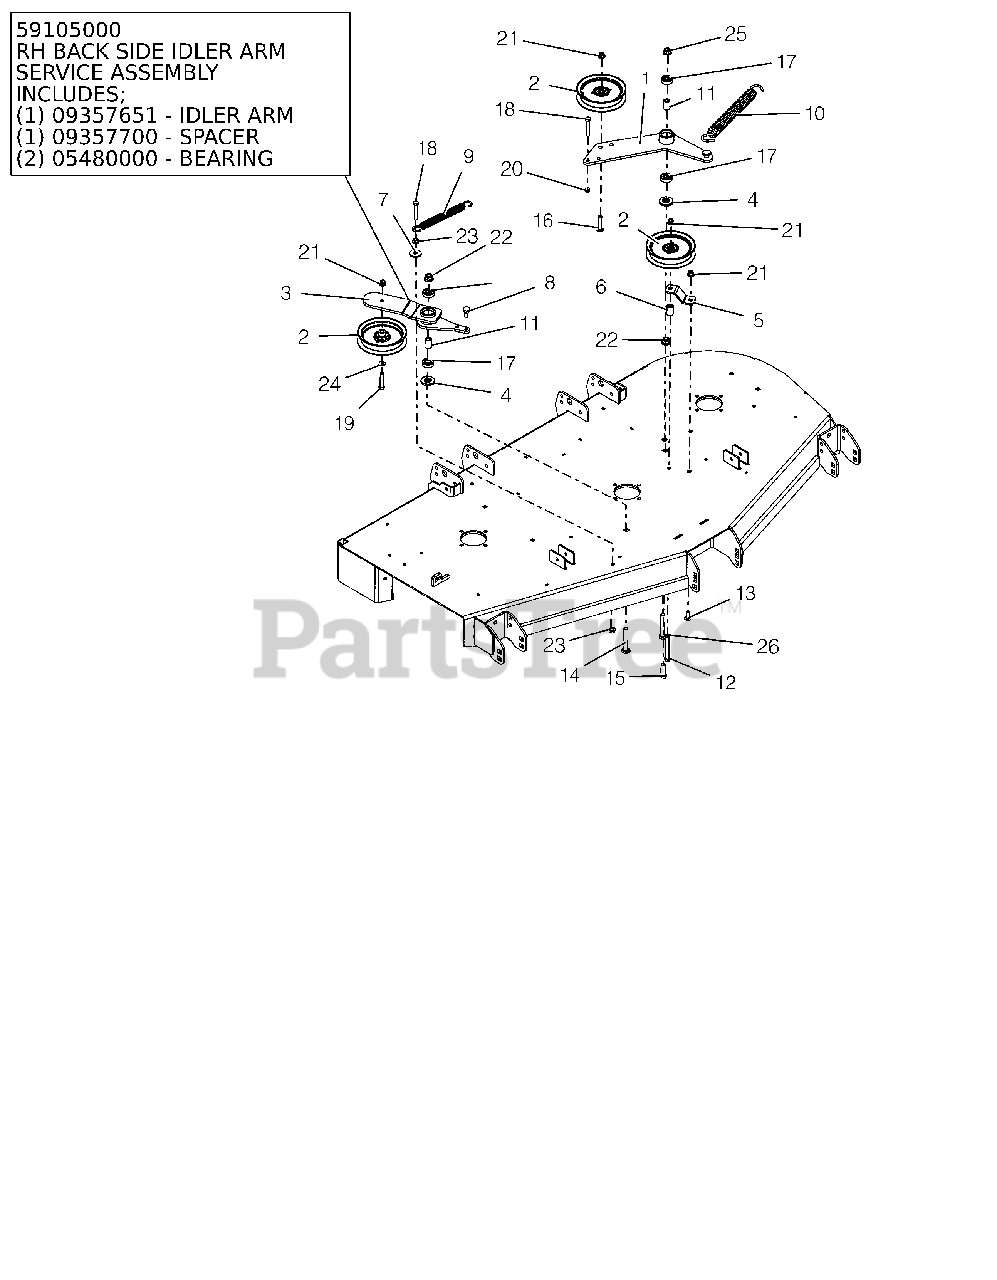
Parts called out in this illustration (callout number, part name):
1	DECK PTO IDLER ARM WLDMT - BLK
2	IDLER, FLAT 5.00"
3	DECK RH IDLER ARM WMT - BLK
3	RH BACKSIDE IDLER ARM ASSEMBLY
3	SPACER .510 X .75 X 1.1485
3	BRG-BALL .50X1.38X.438 SEALED
4	SPACER, IDLER ARM
5	PTO FIXED IDLER MTG BRKT -RED
6	BUSHING, SLV .380X.750X1.190
7	WSHR-FL-STL .406X1.375X.135 YZ
8	BLT,SHLDR EP .38-16X.30 HEX YZ
9	SPRING, EXTENSION
10	SPRING, EXTENSION
11	SPACER .510 X .75 X 1.1485
12	@BLT-HEX .38-16X3.25 GR5 YWZC
13	@BLT-RDHDSHSQNK.38-16X1.0 G5YZ
14	BLT,RDHDSQSHNK.50-13X3.25 G5YZ
15	@BLT-HEX .50-13X1.50 GR5 YWZC
16	BLT-RDHDSQNK .38-16X2.00 SHTYW
17	BRG-BALL .500X1.38X.437
18	@BLT-HEX .38-16X2.25 GR5 YWZC
19	@BLT-HEX .38-16X2.00 GR5 YWZC
20	NUT-HEX-JAM .375-16 YWZC
21	@NUT-LK-NYL-FLG .38-16 YWZC
22	@NUT-LK-NYL-FLG .50-13 YWZC
23	@NUT-SPNLK-FLG .375-16 YWZC
24	@WSHR-FL-STL.406X.812X.065 YWZ
25	NUT-LK-CTR-FLG .50-13 YWZC
26	@BLT-HEX .50-13X3.00 GR5 YWZC
